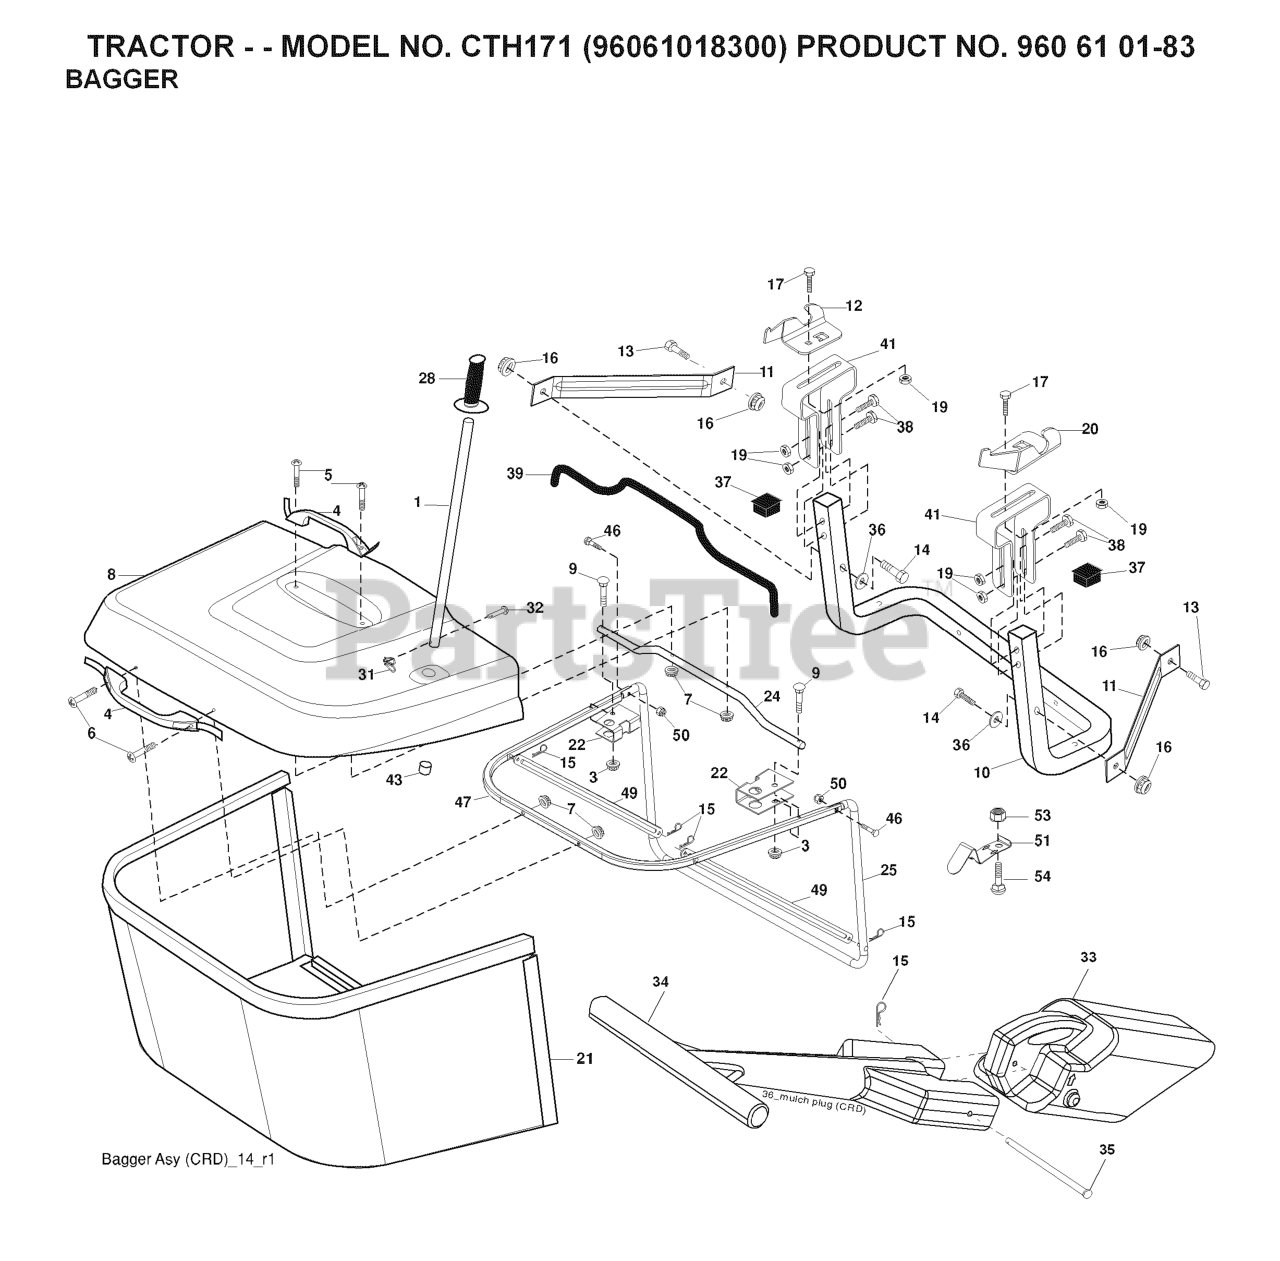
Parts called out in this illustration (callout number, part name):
1	TUBE HANDLE
3	NUT T
4	HANDLE.BAGGER.W/LVRS.BLK.CRD
5	SCREW.PAN.HEAD
6	REPL BY 532 75 00-29
8	COVER.PNT.BGR.CRD.WSLOTS.MS668
9	Bolt Carriage 1/4-20 x 2.25d x Gr.5
10	TUBE
11	BRACKET.SUPPORT.UPPER.BAG.CRD
12	BRKT PIVOT
14	BOLT-HEX EAK
15	RETAINER-SPRNG RB
16	NUT LOCK FLG 3/8-16 UNC
17	RP BOLT 5/16-18 X3/4 ZN/YEL GR
19	NUT LOCK HEX FLANGE 5/16-18
20	BRKT.PIVOT.RH.CRD
21	BAGGER.ASM.CRD.2007
22	BRKT.SIDE.BAG.CRD
24	TUBE.PIVOT.BAG.CRD.BLACK
25	PIPE
28	GRIP.HANDLE.BLACK
31	RETAINER CLIP
32	RIVET,DRILLED
33	PLUG.MULCHER.92 CRD
34	HANDLE.MULCHER.92.CRD (2 2)
36	WASHER
37	Plug Support Bagger CRD
38	BOLT.5/16-18X2.5
39	SEAL.TRIM.37'
41	BRKT.VERT.ADJ.BAGGER.CRD
43	PLUG, TUBING END
46	BOLT.CARRIAGE.5/16-18
47	PIPE
49	ROD
51	LATCH
53	NUT
54	BOLT
